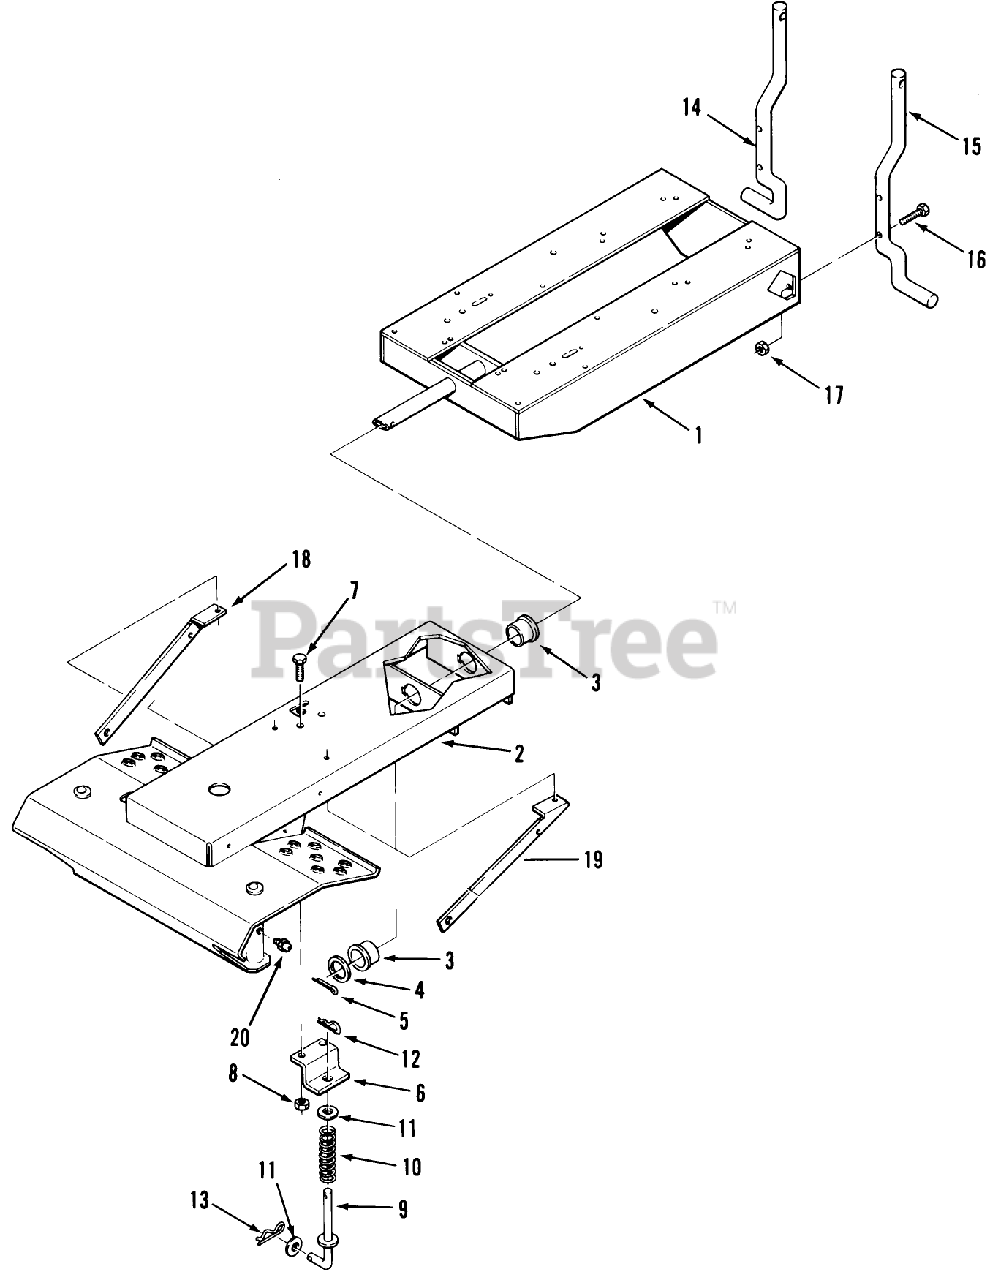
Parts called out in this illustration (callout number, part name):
10	SPRING-COMPRESSION
12	Hairpin Cotter
13	Hairpin
14	REAR ROD RH *B
15	REAR ROD LH *B
